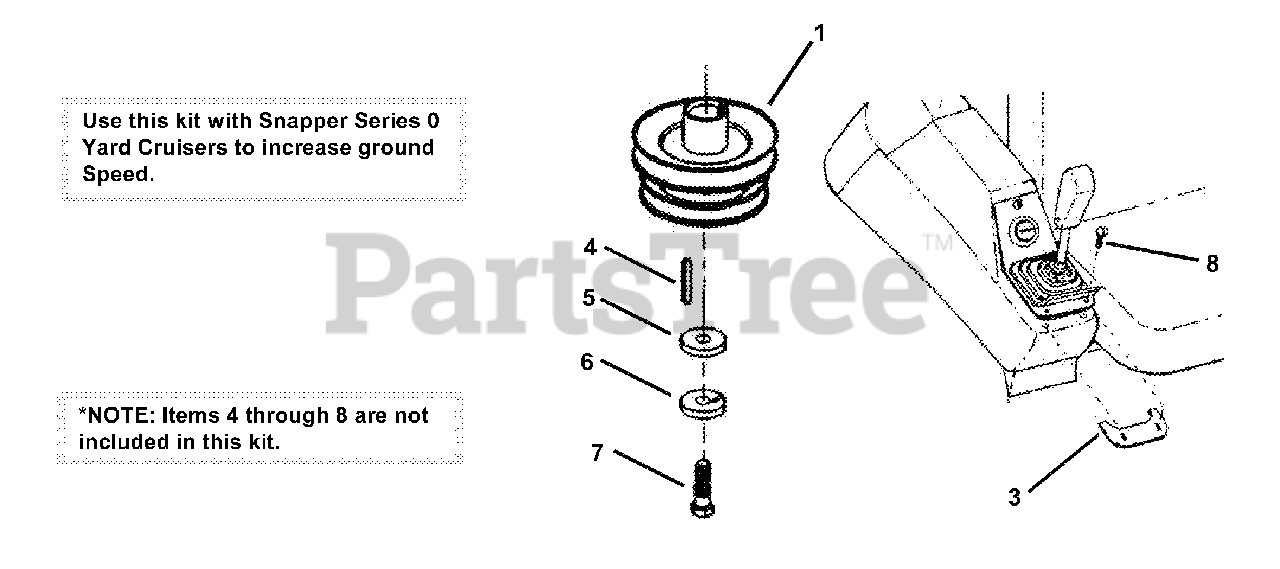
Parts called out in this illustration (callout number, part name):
1	ASSEMBLY, Engine Pulley
3	STOP, Joystick
4	KEY, 1/4" Square x 2"
5	SPACER, Clutch
6	WASHER, 7/16" Split Lock
7	SCREW, 7/16-20 x 1-1/2" Hex Head Cap, Grade 5
8	SCREW, 1/4-20 x 5/8" Pan Head Self-Tapping
